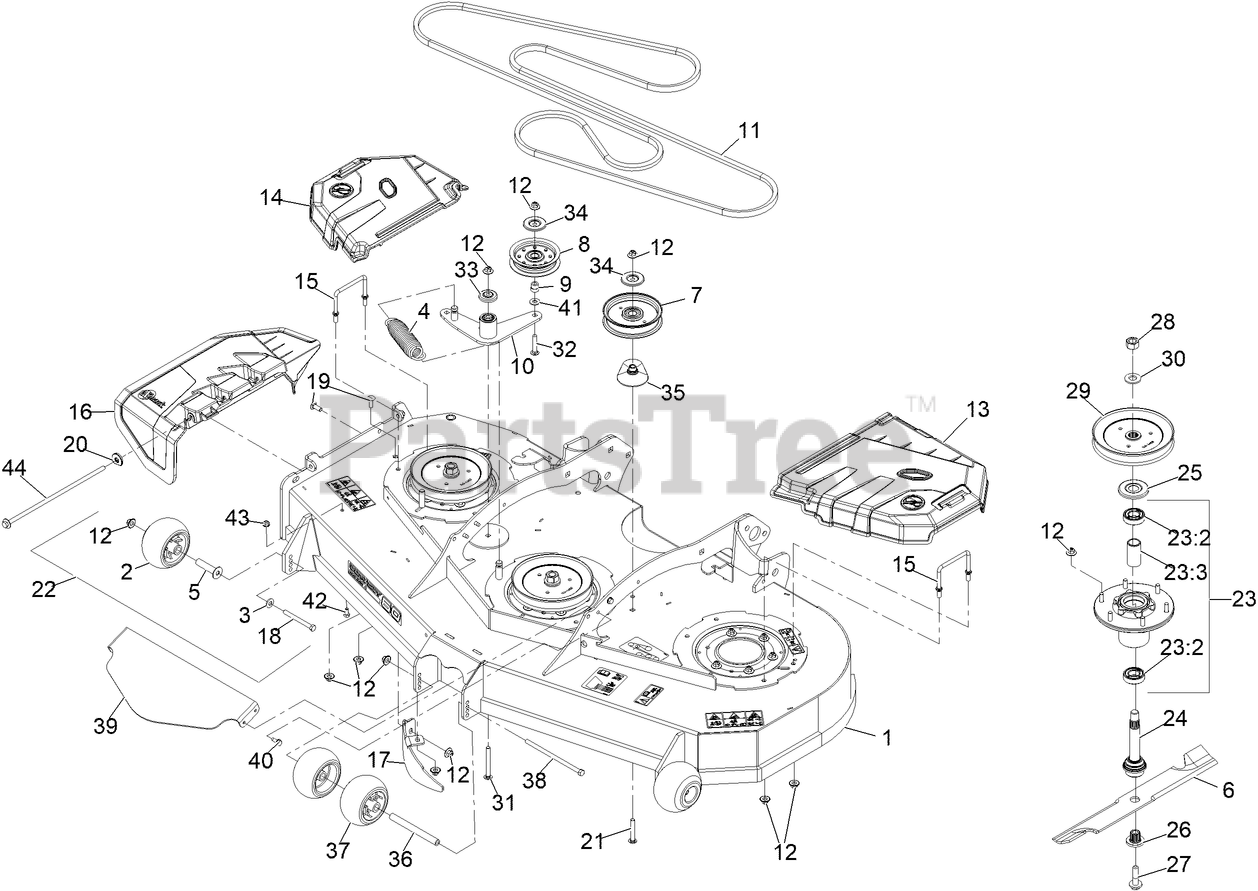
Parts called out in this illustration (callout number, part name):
1	ASM-DECK W/DECALS 604
2	ROLLER-SCALP, ANTI
3	WASHER-BELLEVILLE
4	SPRING-EXTENSION
5	AXLE, ROLLER
6	Blade-Extreme 2, 20.50"
7	Pulley-Idler, Flat
9	BUSHING,IDLER
10	IDLER ARM ASM W/BEARINGS
11	BELT-V
12	Nut-Nyloc 3/8-16 Flg
13	SHIELD, LT
14	SHIELD, RT
15	WIREFORM-COVER
16	Chute-Deck Discharge
17	DOGLEG - LZ60
18	SCREW-HH 3/8-16 X 3 3/4 GR 8
19	SCREW-CARR
20	Retainer, Chute
21	SCREW-CARR
22	KIT, ANTI-SCALP ROLLER
23	ASM-CUTTER HSG WITH BEARINGS
23:2	BEARING-BALL
23:3	SPACER-BEARING
24	ASM-SPINDLE AND SEAL
25	GUARD-BEARING, TOP
26	BUSHING,SPLINED
27	SCREW,SEMS 1/2-20 X 2.19
28	NUT-HEX
29	SHEAVE,BLADE DRIVE 7.25
31	SCREW-CARR
32	SCREW-CARR
33	GUARD-TOP
34	SHIELD-DUST
35	SPACER-PULLEY
36	SPACER-WHEEL
37	ROLLER-SCALP, ANTI
38	SCREW-HH
39	Guard-Front Deck
40	SCREW-THD ROLL, HWH
41	WASHER-FLAT
42	SCREW-HH
43	NUT-HF, NI
44	Pin, Chute
